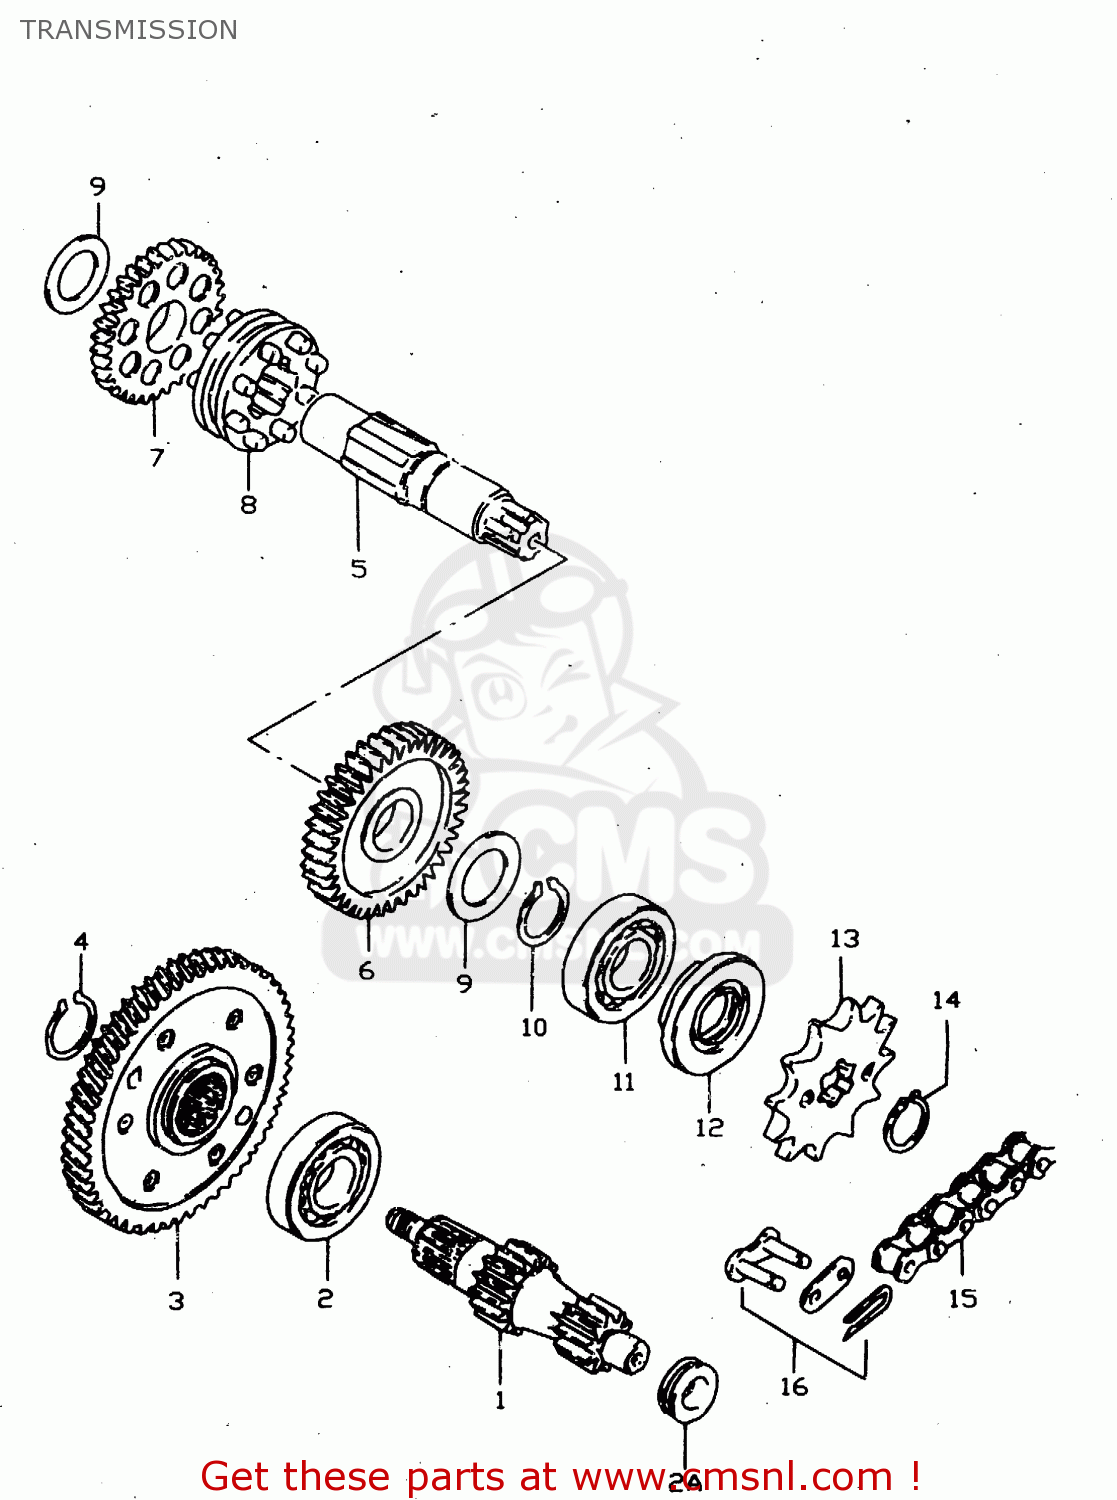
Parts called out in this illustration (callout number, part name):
1	SHAFT,COUNTER
2	BEARING(17X40X12)
2A	BUSH
3	GEAR ASSY,PRI DRIVEN
4	CIRCLIP
5	SHAFT,DRIVE
6	GEAR 1ST DRIVEN
7	GEAR 2ND DRIVEN
8	WHEEL,1ST GEAR
9	WASHER,THRUST
10	CIRCLIP
11	BEARING(17X40X12)
12	OIL SEAL (17X29X7)
13	SPROCKET,ENGINE
14	CIRCLIP 16MM
15	CHAIN,DRIVE
16	JOINT
